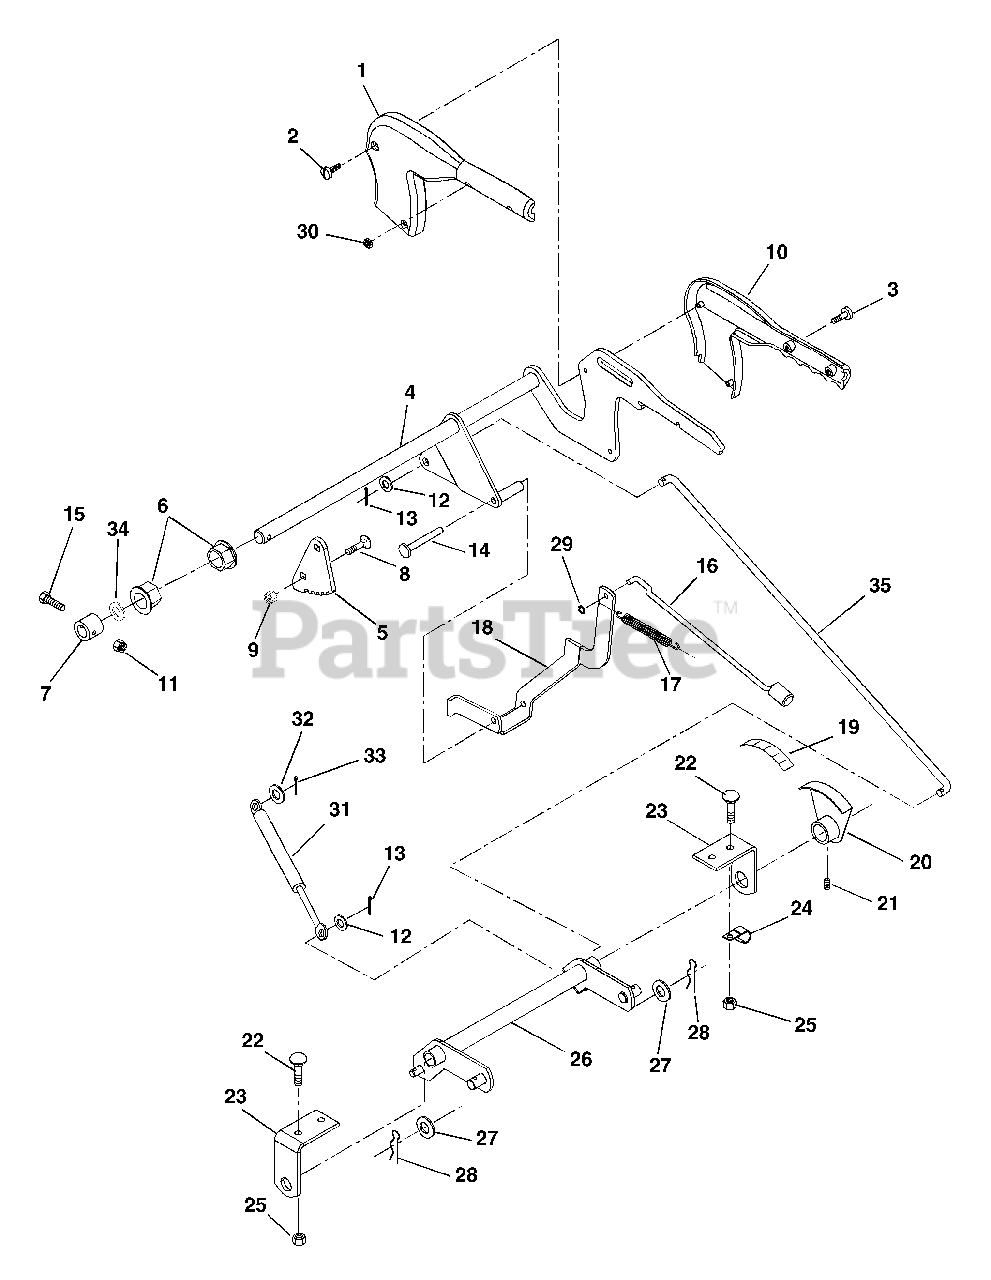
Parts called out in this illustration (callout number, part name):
1	COVER - LIFT RH
2	SCR-TAP 10-16X1.125HI-LOTPHBL
3	SCR-MCH 10-24X.62 P/HD
4	LEVER, LIFT
5	QUADRANT, LIFT
6	BSHG-FLG .750X.873HEXX.53X1.18
7	SPACER-1.25X1.12X.75 W/HOLE
8	@BLT-RDHDSQNK .31-18X.75 G5YZ
9	@NUT-LK-TOP-FLG .31-18 YWZC
10	COVER - LIFT LH
11	@NUT-LK-CTR .25-20 YWZC
12	@WSHR-FL-STL.406X.812X.065 YWZ
13	@PIN-CTR .12X1.00 EXTPRSQCT YZ
14	PIN, PIVOT .312 X 2.56
15	@BLT-HEX .25-20X1.50 GR5 YWZC
16	PIN, LIFT
17	SG-TENS .048X.44X2.25 WLD 9
18	LEVER, DETENT
19	DECAL, INDICATOR
20	INDICATOR, DECK HEIGHT(ASSY.)
21	SCR-SET .25-20X.25 SKHCUP OH
22	BLT-RHHDSQSHNK .38-16X.75 G2YZ
23	BRACKET, CENTER LIFT
24	J-CLAMP
25	@NUT-SPNLK-FLG .375-16 YWZC
26	LEVER, CENTER LIFT
27	WSHR-FL-STL .630X1.005X.062 YZ
28	PIN-HAIR-EXT .12X.31X2.37 YWZC
29	RG-RTNG-EXT .250X.010
30	NUT,10-24 LOW CROWN, ACORN
31	SPRING, GAS (100 LB)
32	@WSHR-FL-STL.38X.875X.083 YWZC
33	PIN-HAIR INT .08X.18X1.18 YWZC
34	@WSHR-FL-STL.812X1.50X.135YWZC
35	LINK, LIFT
